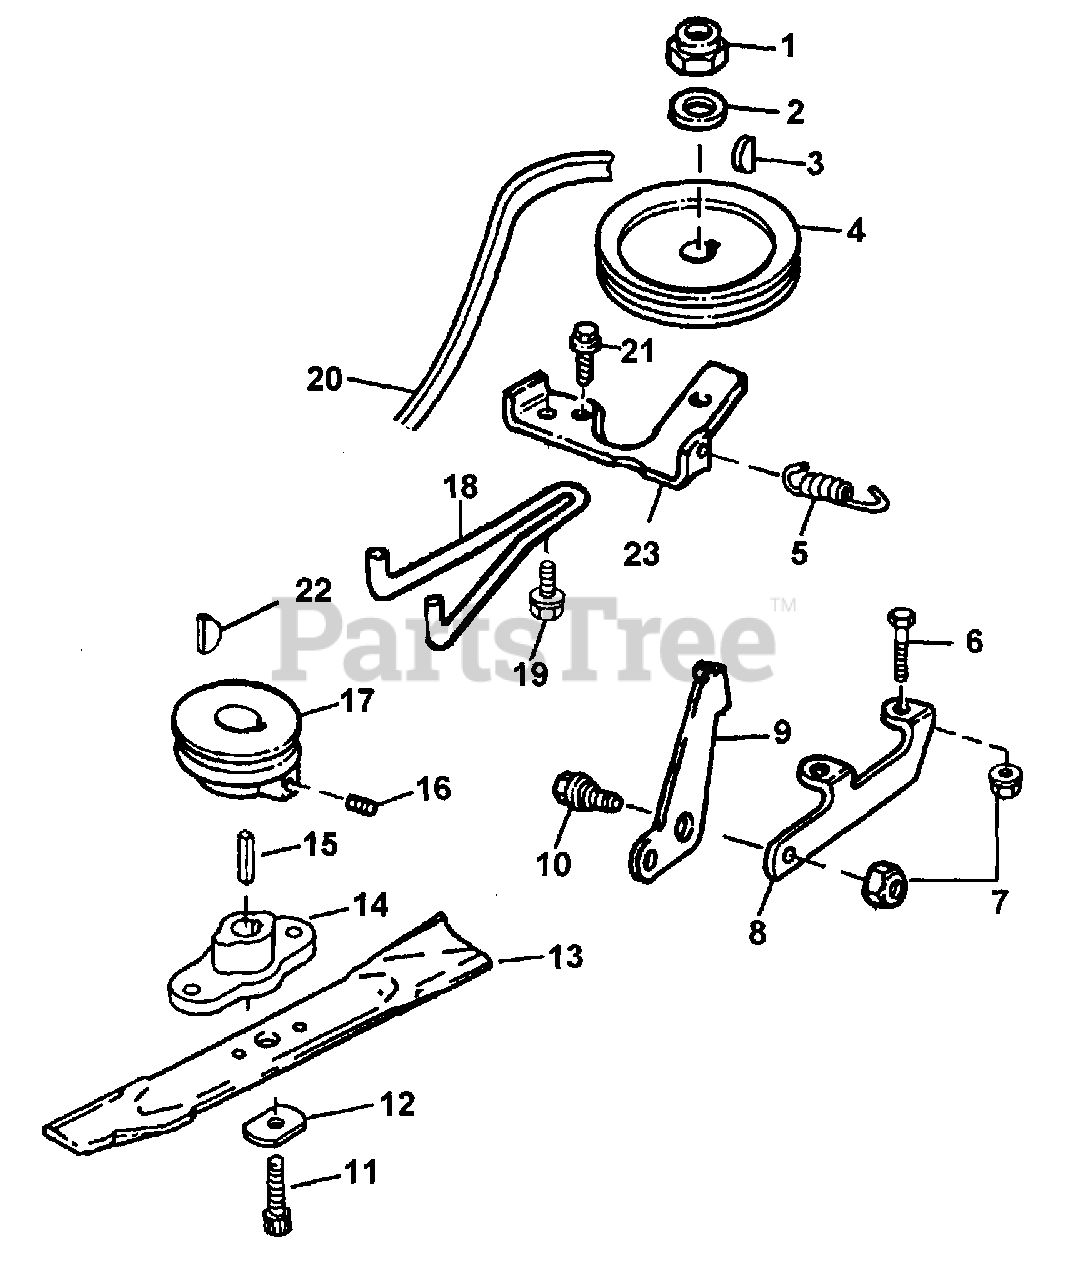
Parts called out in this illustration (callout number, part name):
1	NUT
2	WASHER
3	KEY
4	PULLEY, Gearbox
5	SPRING
6	SCREW
7	NUT, Lock
8	ARM
9	LEVER
10	BOLT, Shoulder
11	BOLT, Blade
12	WASHER, Blade
14	ADAPTER, Blade
15	KEY, Square
16	SCREW, Set
17	PULLEY, Crankshaft
18	GUIDE, Belt
19	BOLT
20	BELT, Drive
21	SCREW
22	KEY, Woodruff
23	GUIDE, Rear Belt
